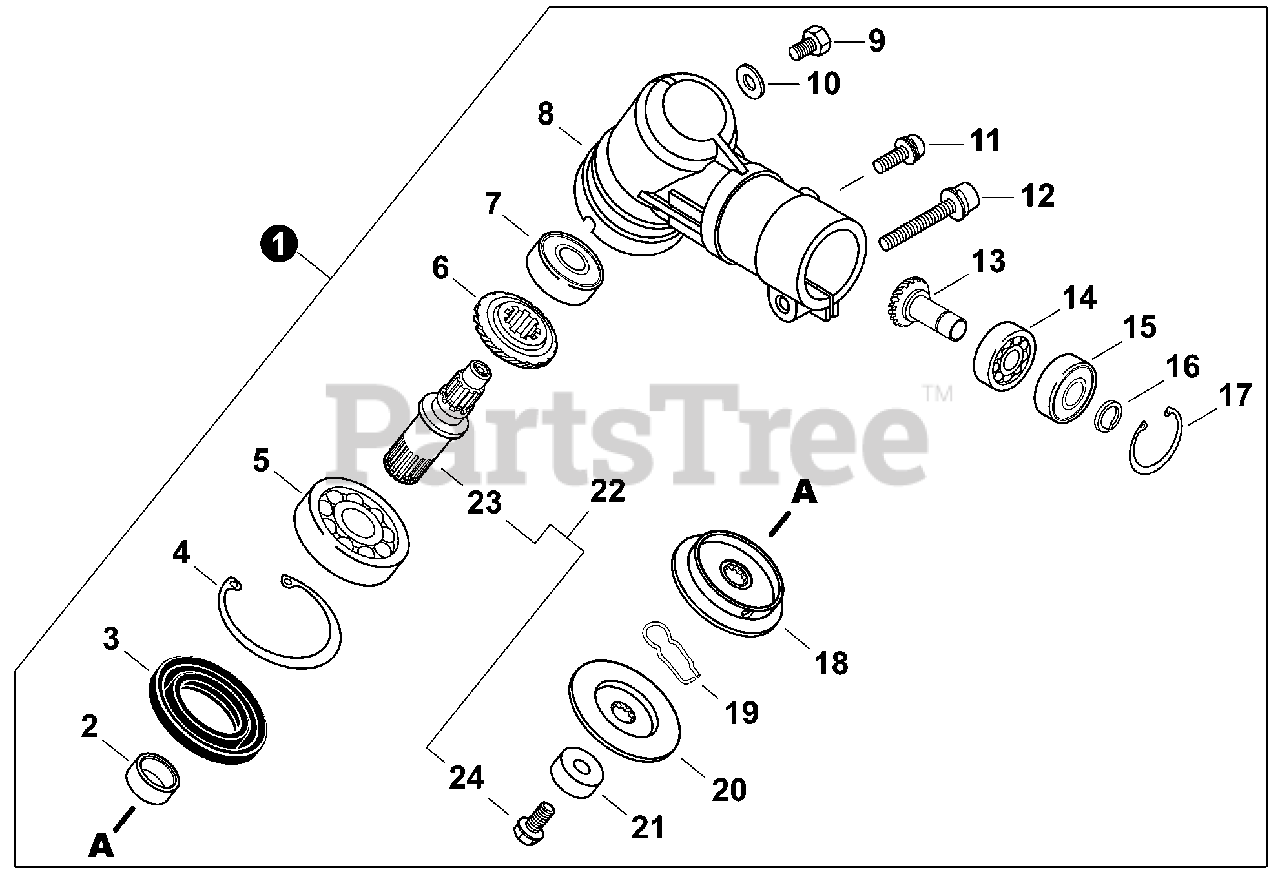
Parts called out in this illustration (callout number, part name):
1	GEAR CASE ASSY
2	COLLAR
3	SEAL, OIL
4	RING, SNAP Ø35
5	BEARING, BALL 6202
6	GEAR, BEVEL
7	BEARING, BALL 6000DDU
8	HOUSING, GEAR CASE
9	BOLT M6×10
10	WASHER
11	BOLT M6×14
12	BOLT M6×28
13	PINION ASSY, BEVEL
14	BEARING, BALL 6001
15	BEARING, BALL 6001ZZ
16	RING, SNAP Ø12
17	RING, SNAP Ø28
18	PLATE, ADAPTOR - UPPER
19	PIN, SLIDE
20	PLATE, ADAPTOR - LOWER
21	GUARD, BOLT
22	GEAR SHAFT SET
23	SHAFT, GEAR
24	BOLT 10×37
